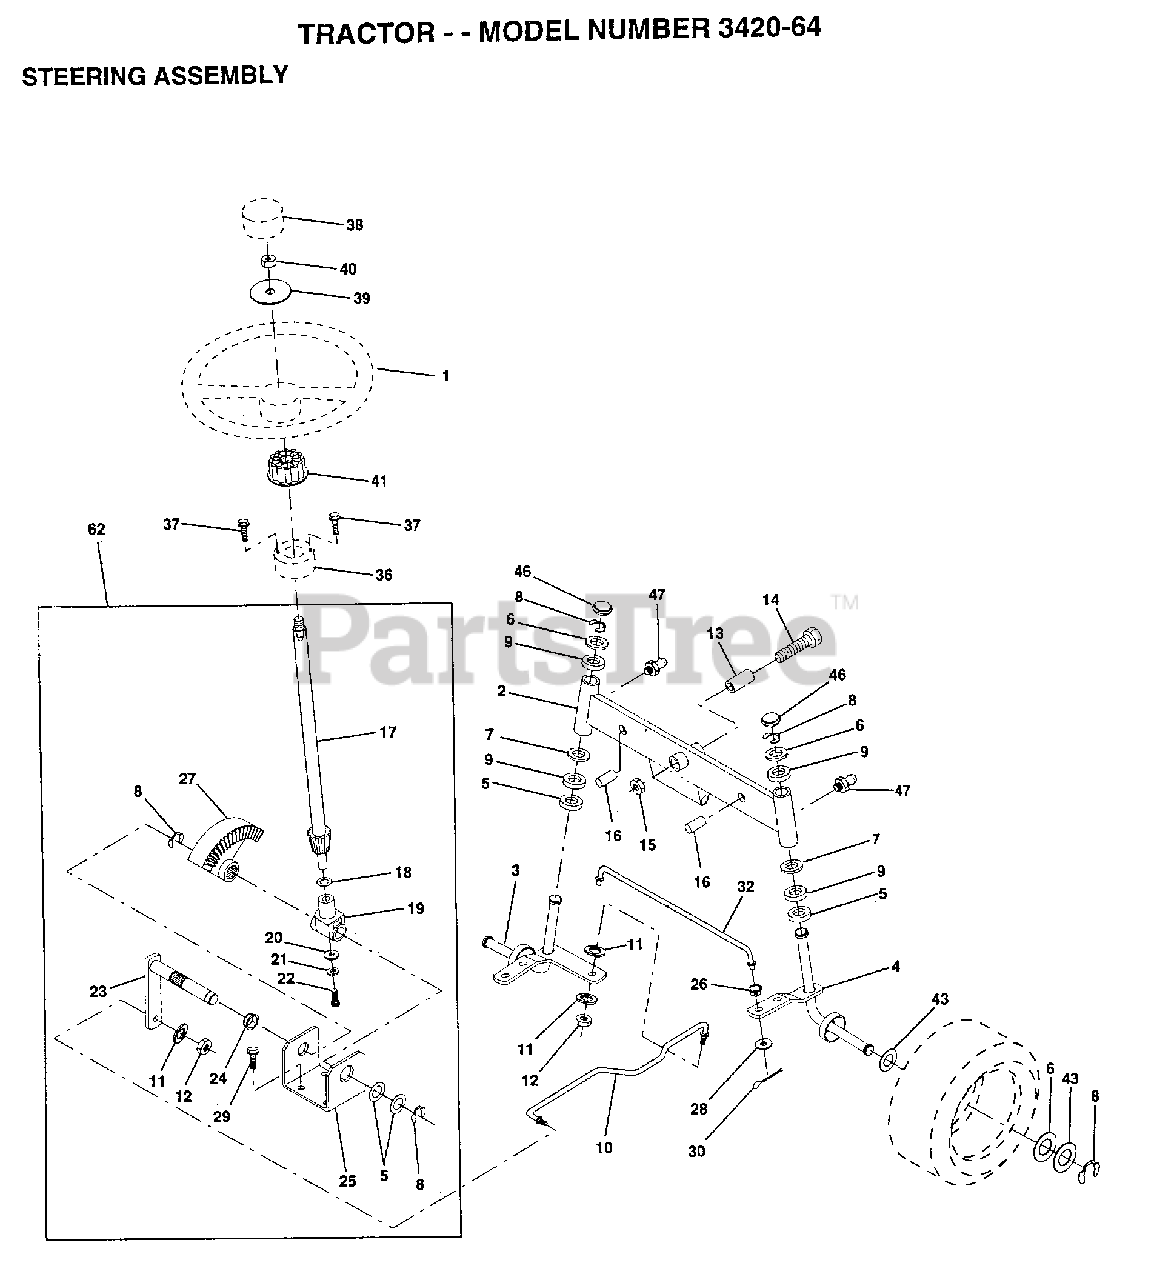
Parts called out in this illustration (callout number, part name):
2	AXLE ASM FRONT
3	SPINDLE LH
4	SPINDLE RH
5	WASHER .T
6	WASHER
7	WASHER
8	RING
9	COL. SRTG. BEAR.
11	LOCKWASHER
13	BEARING
14	BOLT HEX 5/8-11
15	"NUT-LOC,FLANGE LT"
16	AXLE PIN
17	STEERING SHAFT
18	THRUST WASHER
19	SUPPORT.SHAFT
21	LOCKWASHER
22	SCREW.SCKTHD.CAP
24	NYLINER T
25	"BRKT,STEERING"
26	BUSHING.DRAGLINK
27	GEAR SECTOR
28	WASHER
29	SCREW
30	COTTER PIN
32	TIE ROD
36	BUSHING.STRG.3/4
37	"SCREW-TT,10-32 FL"
38	"INSERT,STR WHEEL"
39	WASHER
41	ADAPTER LT
43	WASHER
46	CAP
47	ZERK M
